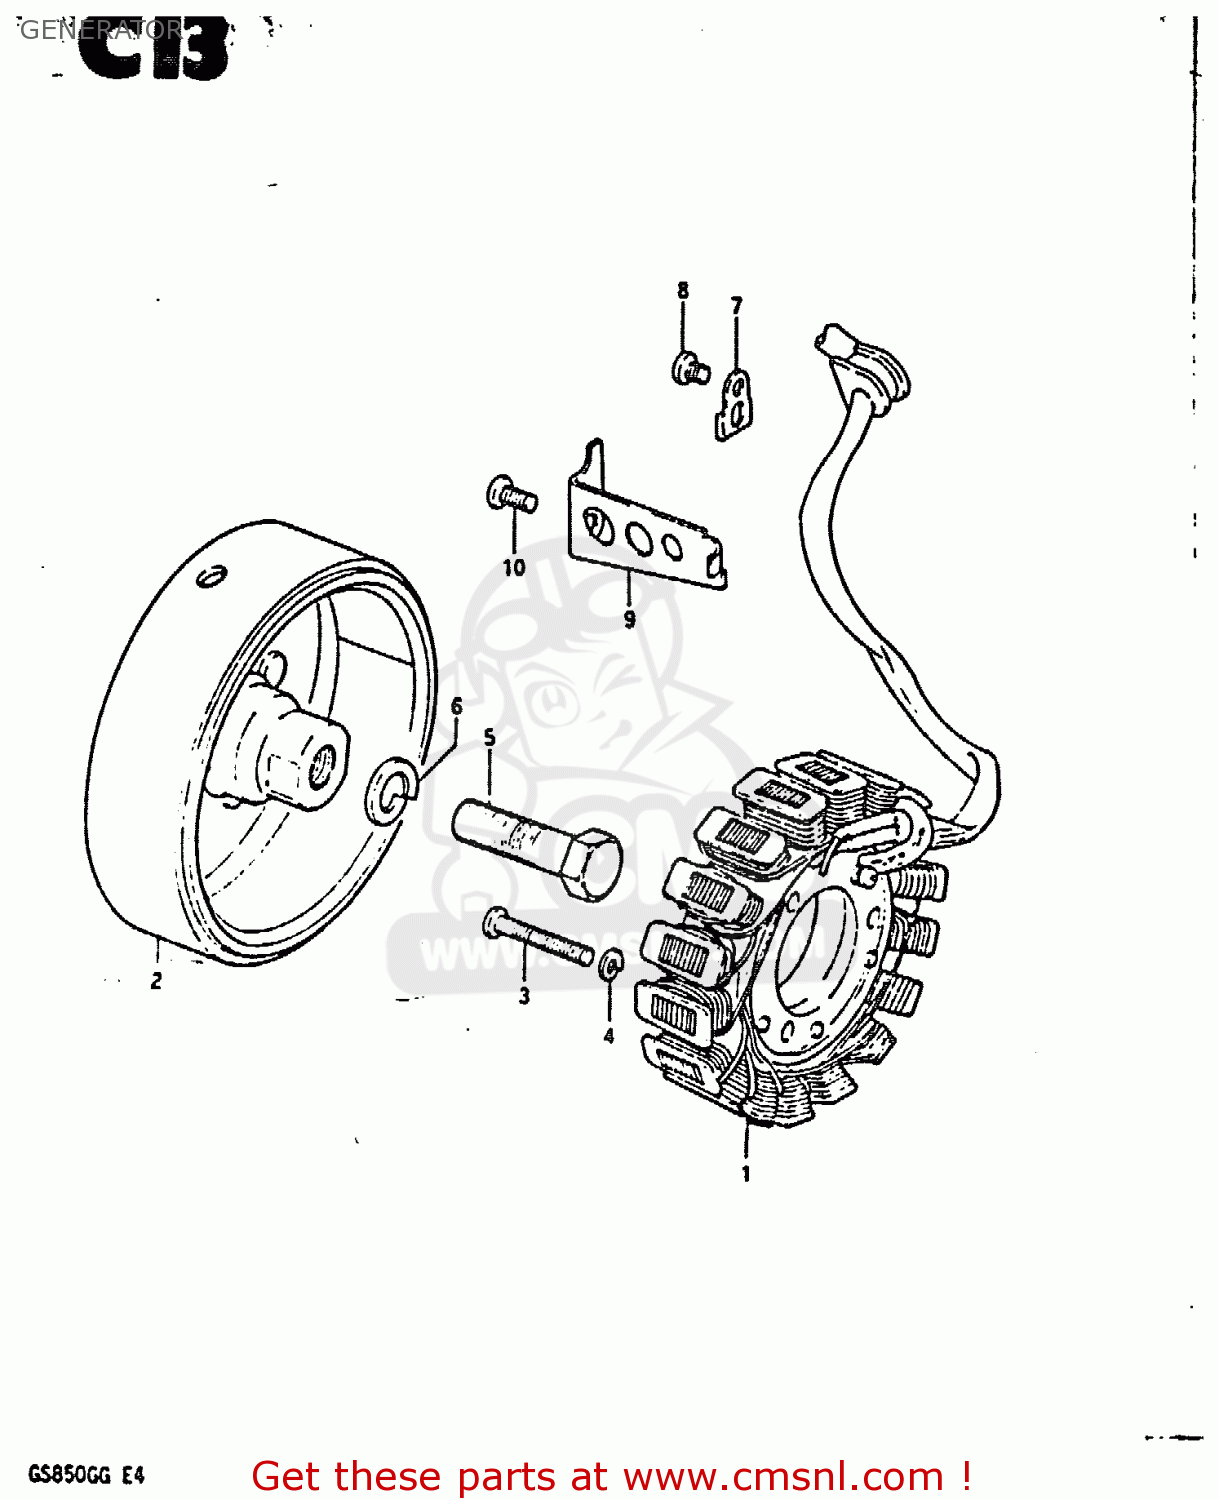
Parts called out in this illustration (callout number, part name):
1	STARTER ASSY
2	ROTOR ASSEMBLY
3	SCREW
4	LOCK WASHER
5	BOLT 12X45
6	WASHER,LOCK 12
7	CLAMP,GENERATOR LEAD WIRE
8	SCREW
9	CLAMP,GENERATOR LEAD WIRE
10	SCREW
